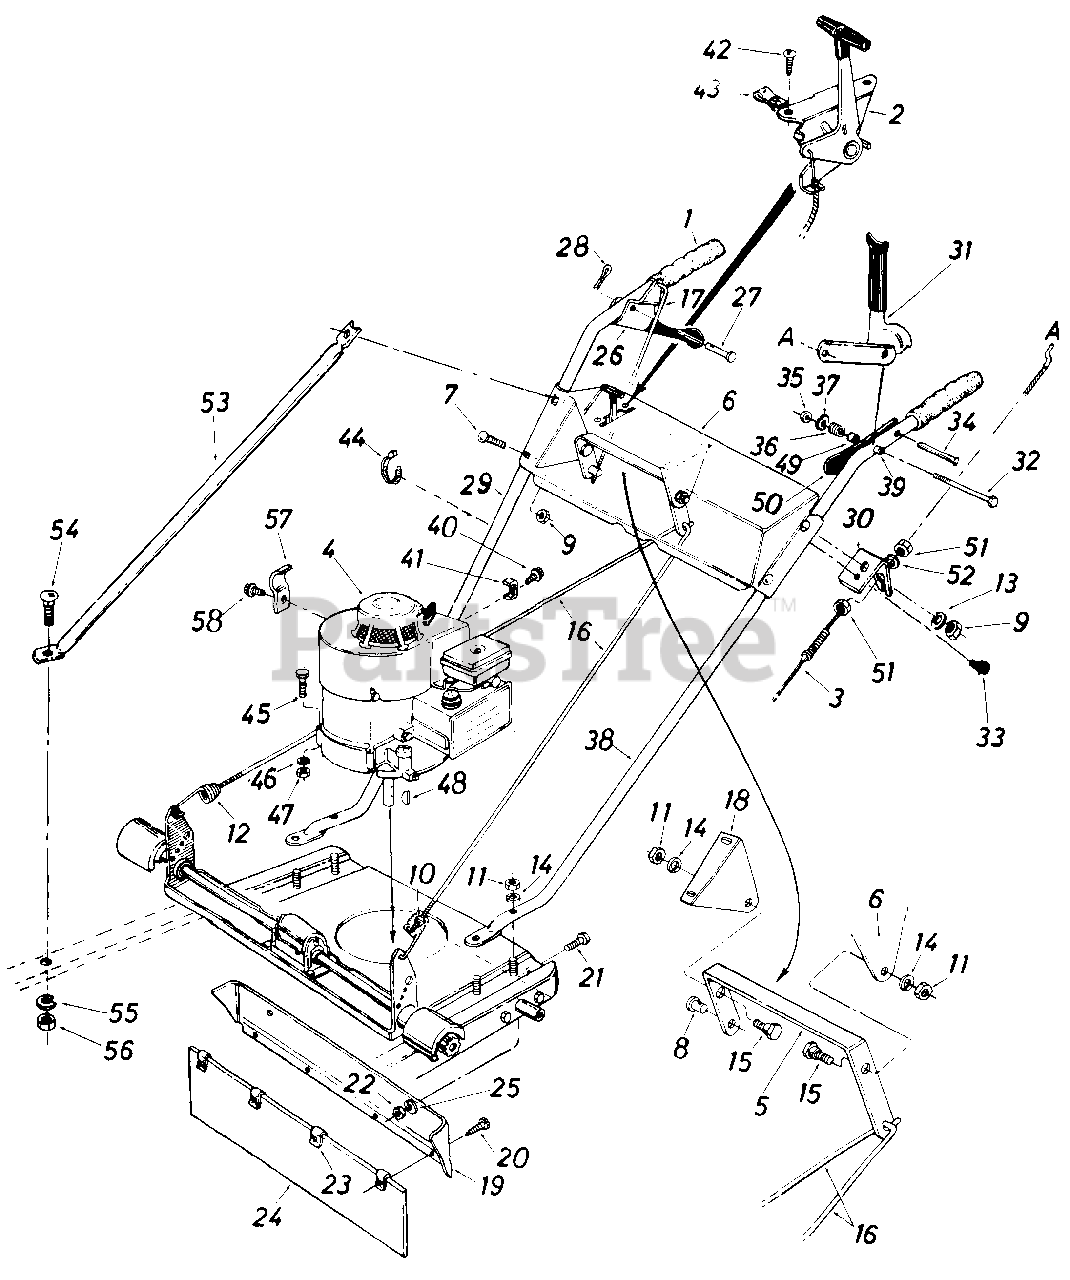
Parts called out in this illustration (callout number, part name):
2	Throttle Control Ass'y. Comp.
3	Clutch Cable 56" Long
4	Engine
5	Link Bracket
6	Handle Panel Ass'y.
7	Carriage Bolt 5/16-18 x 1.75" Lg.*
8	Adj. Ferrule 1/4-20 Thd.
9	Hex Nut 5/16-18 Thd.*
10	Hex Ins. L-Nut 1/4-20 Thd.
11	Hex Nut 3/8-16 Thd.*
12	Extension Spring
13	L-Wash. 5/16" I.D.*
14	L-Wash. 3/8" I.D.*
15	Shld. Bolt .500" Dia. x .295
16	Lockout Rod
17	Rod .214" Dia. x 14.87" Lg.
18	Bracket
19	Drag Shield Adapter
20	Hex B-Tap Scr. #10 x .62" Lg.
21	Hex Bolt 1/4-28 x .62" Lg.*
22	Hex Nut 1/4-28 Thd.*
23	Speed Nut 10Z U-Type
24	Drag Shield 4.65" x 20.0" Lg.
25	L-Wash. 1/4" I.D.*
26	Clutch Grip Ass'y.
27	Clevis Pin .375" Dia.
28	Intern. Cot. Pin 5/16" Dia.
29	R.H. Handle (Chrome)
30	Clutch Cable Brkt.
31	Blade Clutch Grip Ass'y.
32	Hex Bolt 1/4-20 x 2.25" Lg.*
33	Hex Wash. S-Tap Scr. 1/4-20 x .50 Lg.
35	Hex Cent. L-Nut 1/4-20 Thd.
36	Compression Spring .50" O.D. x .50" Lg.
37	Internal Tooth L-Wash.
38	L.H. Handle (Chrome)
39	Spacer.255" I.D.
40	Hex B-Tap Scr. #10 x .38" Lg.
41	Casing Clamp
42	Hex Wash. Hd. AB-Tap Scr. #10 x .50" Lg.
43	Speed Nut 10Z
44	Cable Tie Self Clinching
45	Hex Bolt 5/16-24 x 1.25" Lg.*
46	L-Wash. 5/16" I.D.*
47	Hex Nut 5/16-24 Thd.*
48	#6 Hi-Pro Key 5/32 x 5/8" Dia.
49	Spacer.255" I.D. x .375" O.D.
51	Hex Jam Nut 5/16-24 Thd.
52	L-Wash. 5/16" I.D.*
53	Strut
54	Carriage Bolt 5/16-18 x .62" Lg.*
55	L-Wash. 5/16" I.D.*
56	Hex Nut 5/16-18 Thd.*
57	Casing Clamp
58	Hex Wash-Hd. Tap Scr. #10 x .50" Lg.
8573-000-5	Hardware Pack
8574-000-5	Hardware Pack
